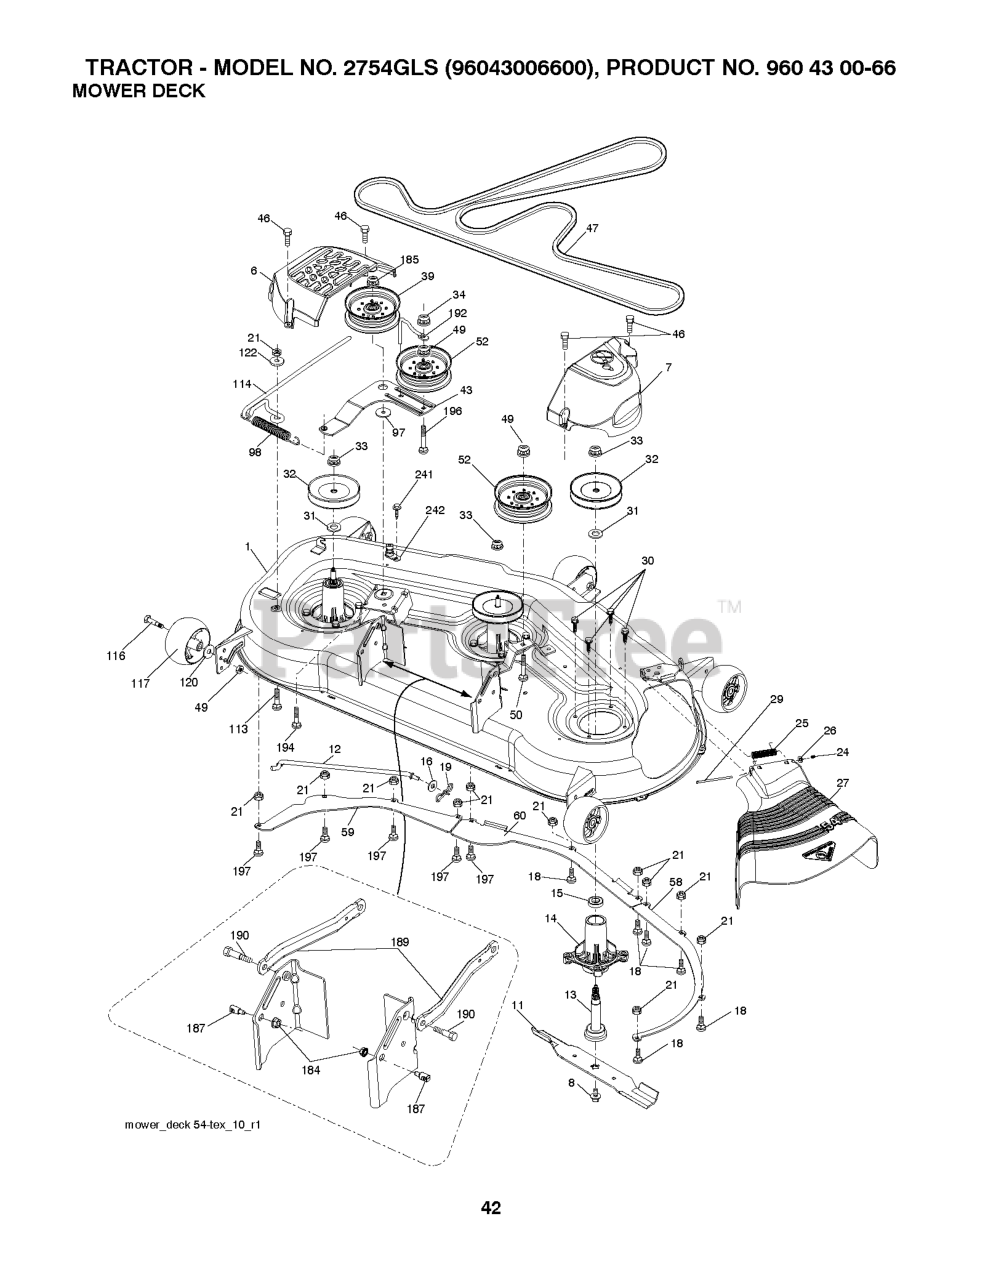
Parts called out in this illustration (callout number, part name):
1	DECK.WLDMNT.W/TUBES.54"MS.422
6	COVER.MANDREL.LH.54"20
7	COVER.MANDREL.RH.54.20
8	BOLT.WASHER.ASM.7/16-2
11	BLADE.BAGGING.54"
12	ROD.ANTI.SWAY.48/54"TE
13	SHAFT ASM MANDREL
14	RP.HOUSING.MANDREL.4PT.
16	WASHER
18	BOLT
19	PIN.COTTER.5/16.BOW TI
21	LOCKNUT
24	CAP-SLEEVE LT
25	SPRING, TORSION
26	NUT PUSH M
27	DEFLECTOR
29	ROD.HINGE
30	SCREW, WASHER HEAD
31	WASHER.SPACER.MANDREL
32	PULLEY/MANDREL
33	NUT.FLANGE.LOCK.TOP
39	RB PULLEY.IDLER.4.50/HUB SPEC
46	SCREW.1/4-20X5/8
47	RP.BELT.DRIVE.54."2006
49	NUT LOCK FLG 3/8-16 UNC
52	PULLEY.IDLER.2006
58	BAFFLE.RIGHT.54"
59	BAFFLE.LEFT.54"
60	BAFFLE CENTER 54" MOWER
98	SPRING, DECK DRIVE
114	ROD TENSION RELIEF
116	BOLT.SHOULDER.3/8-16X3-5/8.
117	RP WHEEL. GUAGE RALLY
120	WASHER
122	BUSHING.RELIEF.TENSION
185	NUT.LOCK.FLANGE.7/16
187	STUD.FASTNER.W/ANTI-ROTATE
188	NUT LOCK HEX FLANGE 5/16-18
189	ARM.SUSPENSION.MOWER
190	BOLT.SHOULDER
192	KEEPER.BELT.IDLER.54"T
194	BOLT.CARR.SQNK.7/16
241	SCREW.TT.#10-32X.5.3/8.FLANGE
242	PORT.WASHOUT
